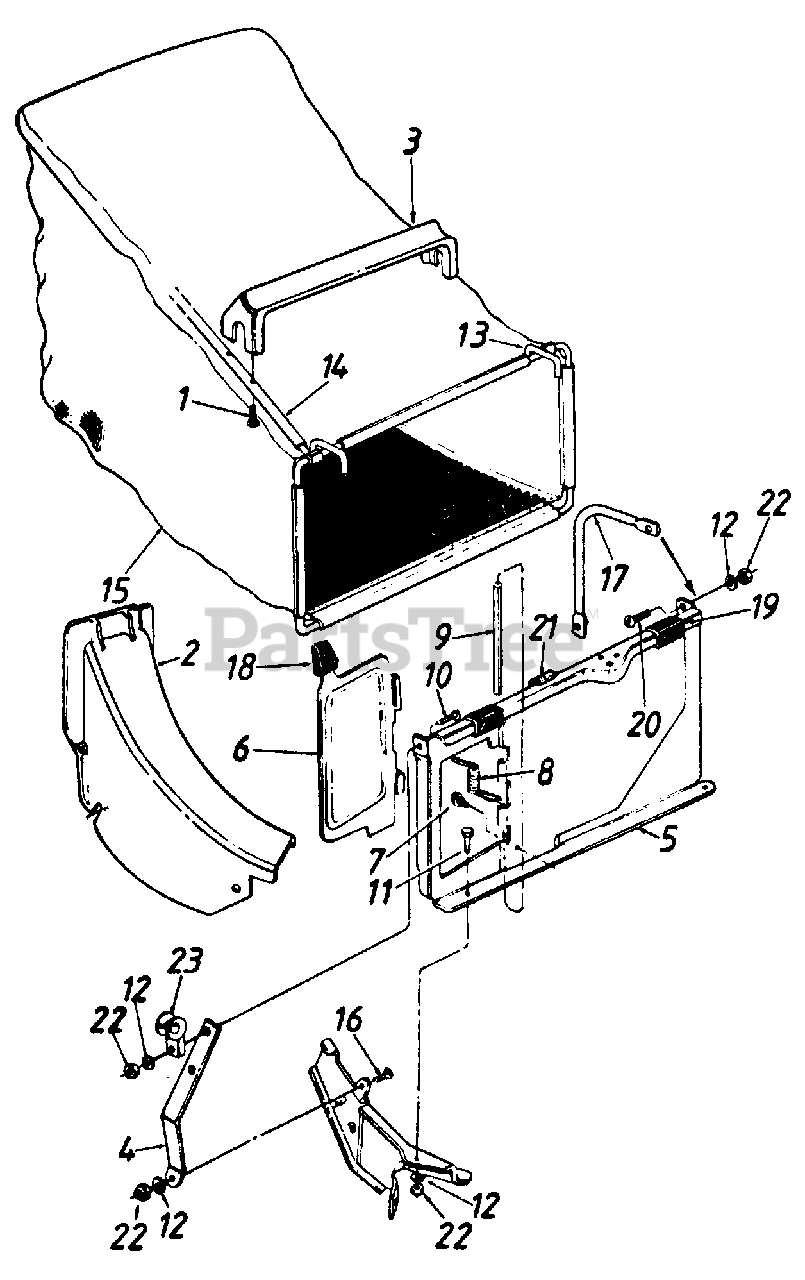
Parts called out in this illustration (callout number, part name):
1	Hex AB-Tap Scr. #12 x 1.25" Lg.
2	Rear Discharge Chute Ass'y.
7	Hex 3-Tap Scr. #10 x .38"
8	Torsion Spring
10	Truss Mach. Scr. 1/4-20 x 3/4" Lg.
11	Hex Bolt 1/4-20 x .50" Lg.
12	L-Wash. 1/4" I.D.
15	21" Rear Discharge Grass Bag
16	Hex Bolt 1/4-20 x .62" Lg.
17	Catcher Panel Support Arm
18	Door Grip
20	Truss Mach. Scr. 1/4-20 x .62" Lg.
22	Hex Nut 1/4-20 Thd.
16862-0638	PANEL ASSY-CATCHER - MTD/TROY-BILT RED (0638)
